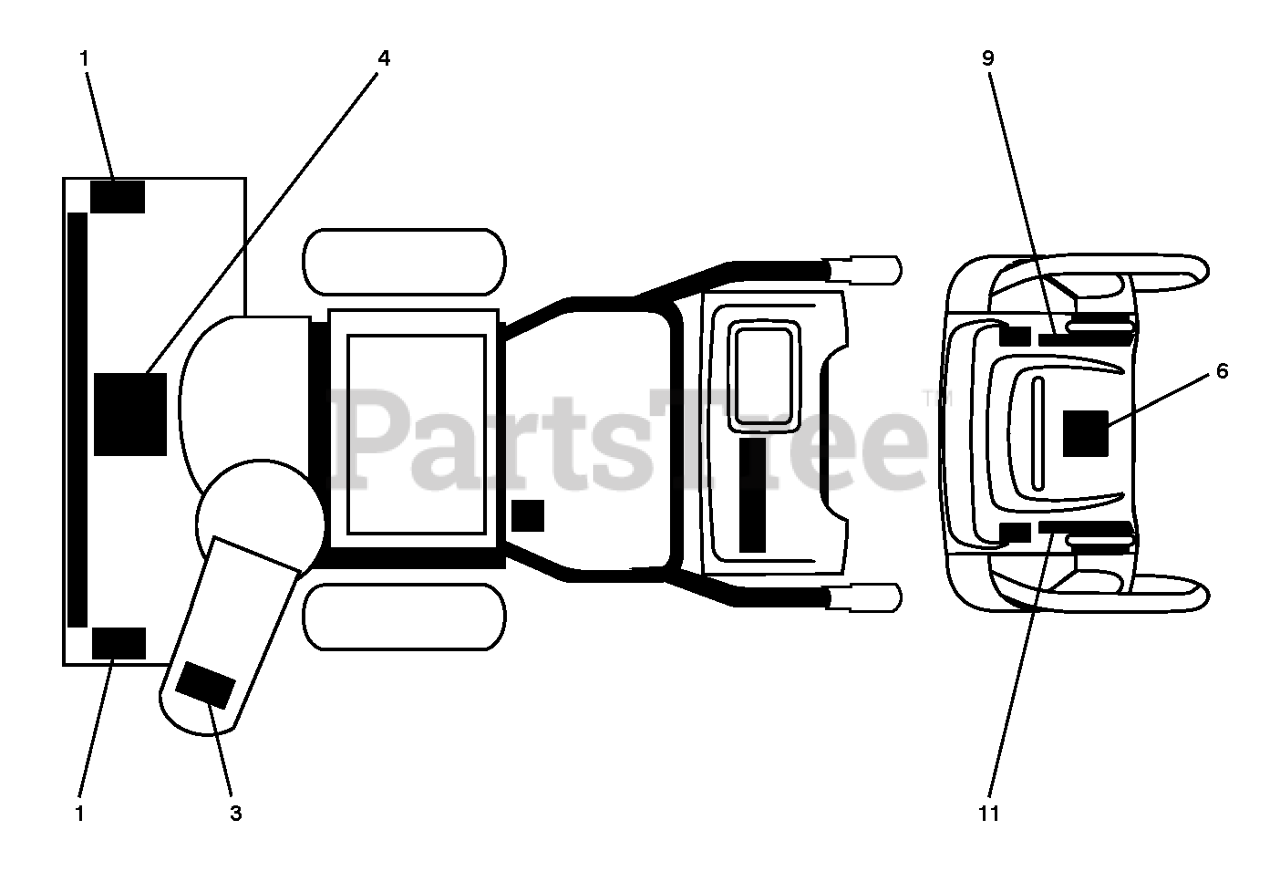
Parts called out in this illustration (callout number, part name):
1	DECAL.SNOWTHR.AUGER
3	DECAL.SNOWTHR.CHUTE.SAFETY
4	DECAL.SNOWTR.READ.OWN.MAN.E/F
6	DECAL.CONSOLE.SNOW.INST.ENG/FR
9	DECAL.CONS.RT.SPD/LEV/PWRST.
11	DECAL.CONS.LT.SPD/LEV/PWRST.
